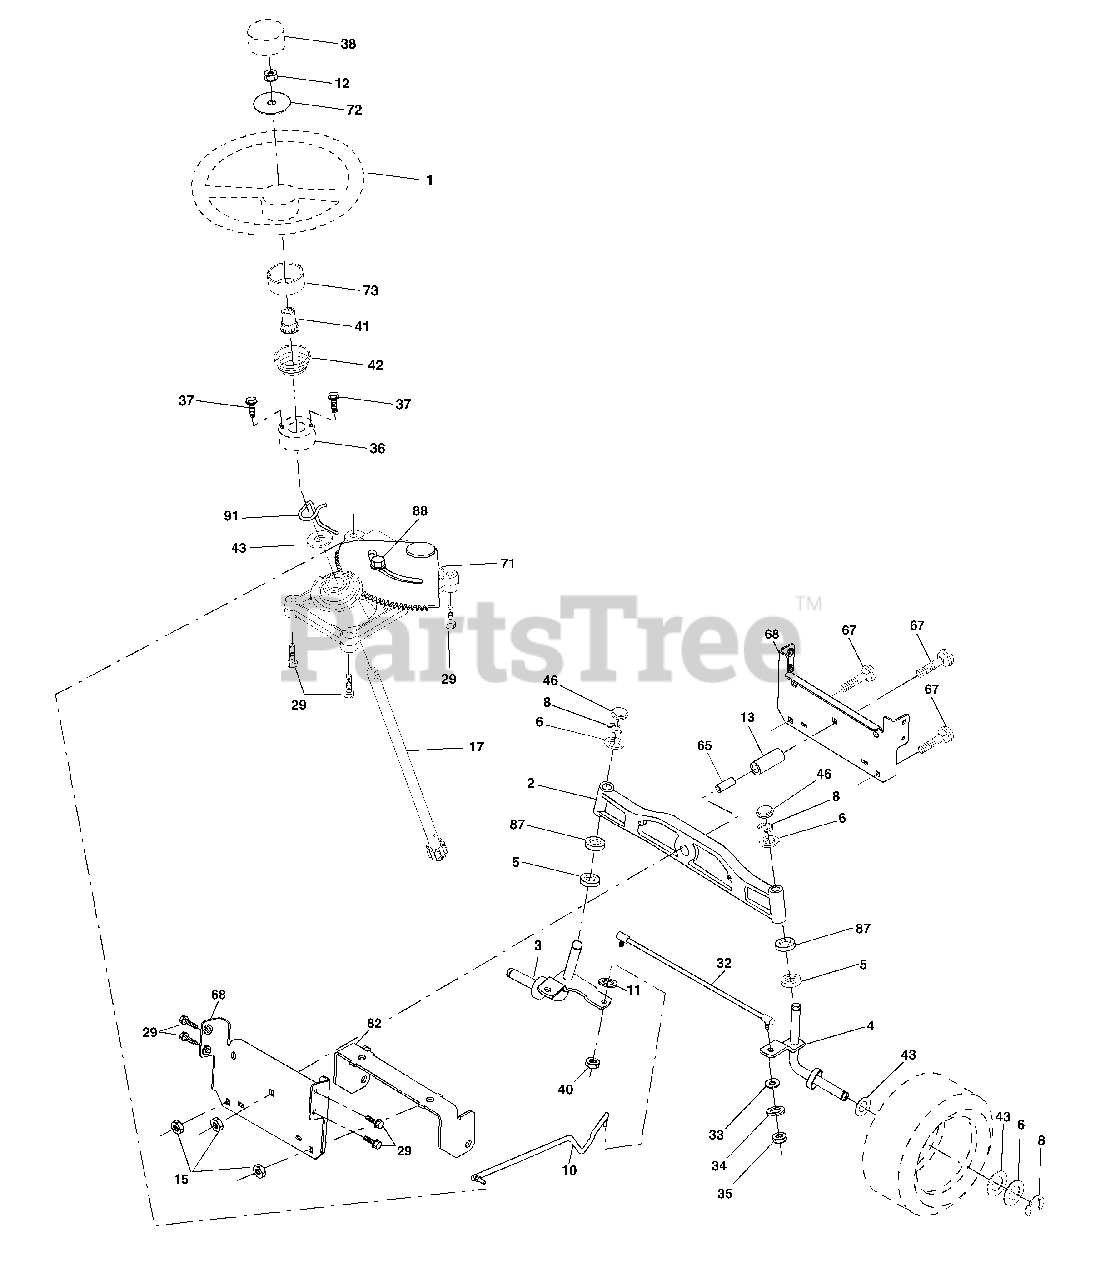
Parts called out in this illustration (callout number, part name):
1	Wheel Steering
2	Axle Cast Lt Machined
3	Spindle Asm LH
4	Spindle Asm RH
5	Bearing Race Thrust Harden
6	Washer 25/32 X 1-5/8 X 16 Ga
8	Ring Klip #t5304-75
10	Link Drag
11	Washer Lock Hvy Hlcl Spr 3/8
12	Nut Hex Jam Toplock 1/2-20 UNF
13	Spacer Brg Axle Front
15	Nut Hex Flange Lock
17	Shaft Asm Strg
29	Screw 3/8-16x3/4
32	Rod Tie
33	Washer 11/32 x 3/4 x 16 Ga.
34	Washer Lock Hry Hlcl Spr 5/16
35	Nut Crownlock 5/16 - 24 UNF
36	Bushing Strg
37	Screw TT #32.5 x 5 x 3/8 Flange
38	Cap Wheel Steer
40	Nut Lock Center 3/8-24 Unf
41	Adaptor Wheel Strg
42	Boot Steering
43	Washer 25/32 X 1 1/4 X 16 Ga
46	Cap Spindle Fr Top Blk
65	Spacer Brace Axle
67	Bolt Rdhd Sqn 3/8-16 x 2-1/4
68	Brace, Axle
71	Steering Asm.
72	Washer 9/16 ID x 1/20 OD 11 Ga.
73	Extension Steering
82	Bracket Susp Chassis Front
87	Washer Flat .781 x 1-1/2 x .14
88	Bolt Shoulder 7/16-20 Unc
91	Clip
